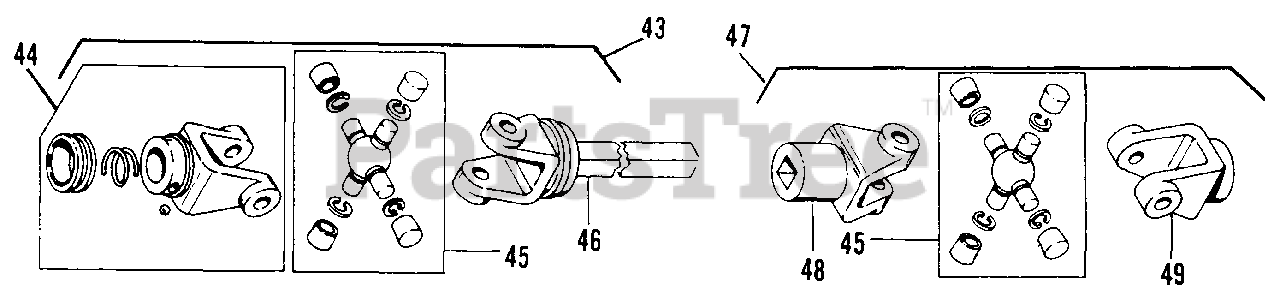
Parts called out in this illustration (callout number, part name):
43	JOINT & SHAFT ASSY
44	YOKE ASSY
45	KIT, Repair
46	YOKE & SHAFT
47	JOINT & TUBE ASSY
48	YOKE & TUBE
